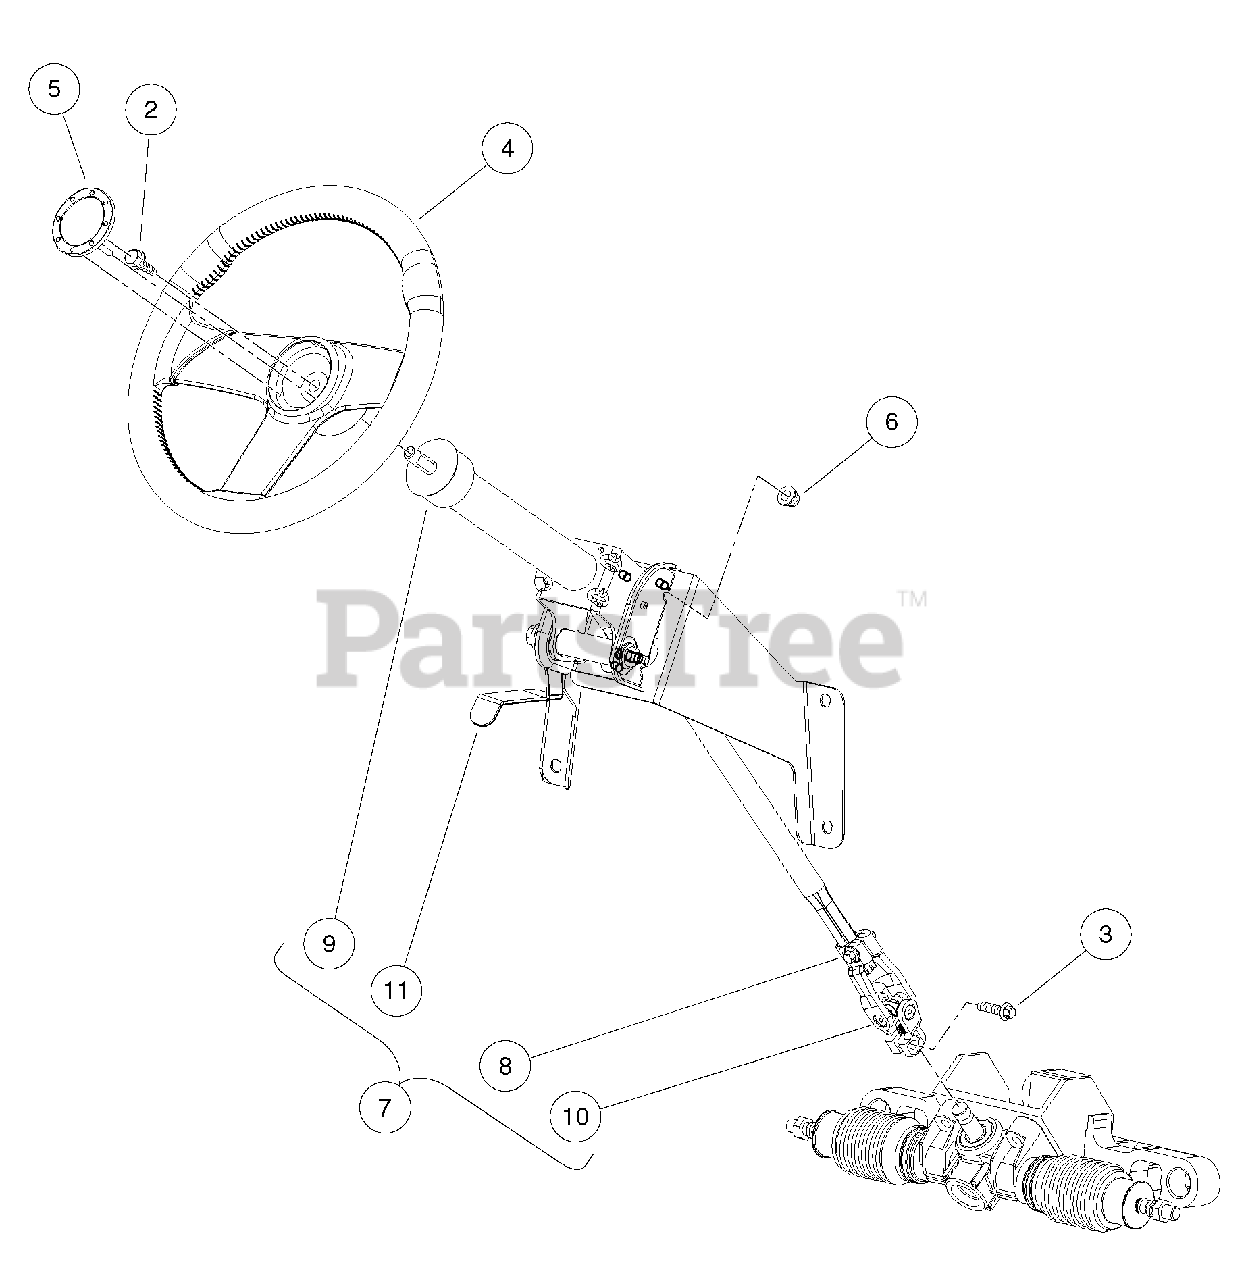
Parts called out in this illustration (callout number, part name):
1	Instl, Steering System
2	Bolt, M10 X 20 Hex Washer Hd
3	Bolt, Flange Head, M8 X 30.0
4	Steering Wheel, Viper, Hex Hub
5	Cap, Steering Wheel, Viper
6	Lock Nut, Flg M8 X 1.25 Nylon
7	Steering Column
8	Bolt, Flange Head, M8 X 30.0
9	Shroud, Steering Column
10	Bolt, M4 X .7 X 60
11	Handle, Steering, Tilt
